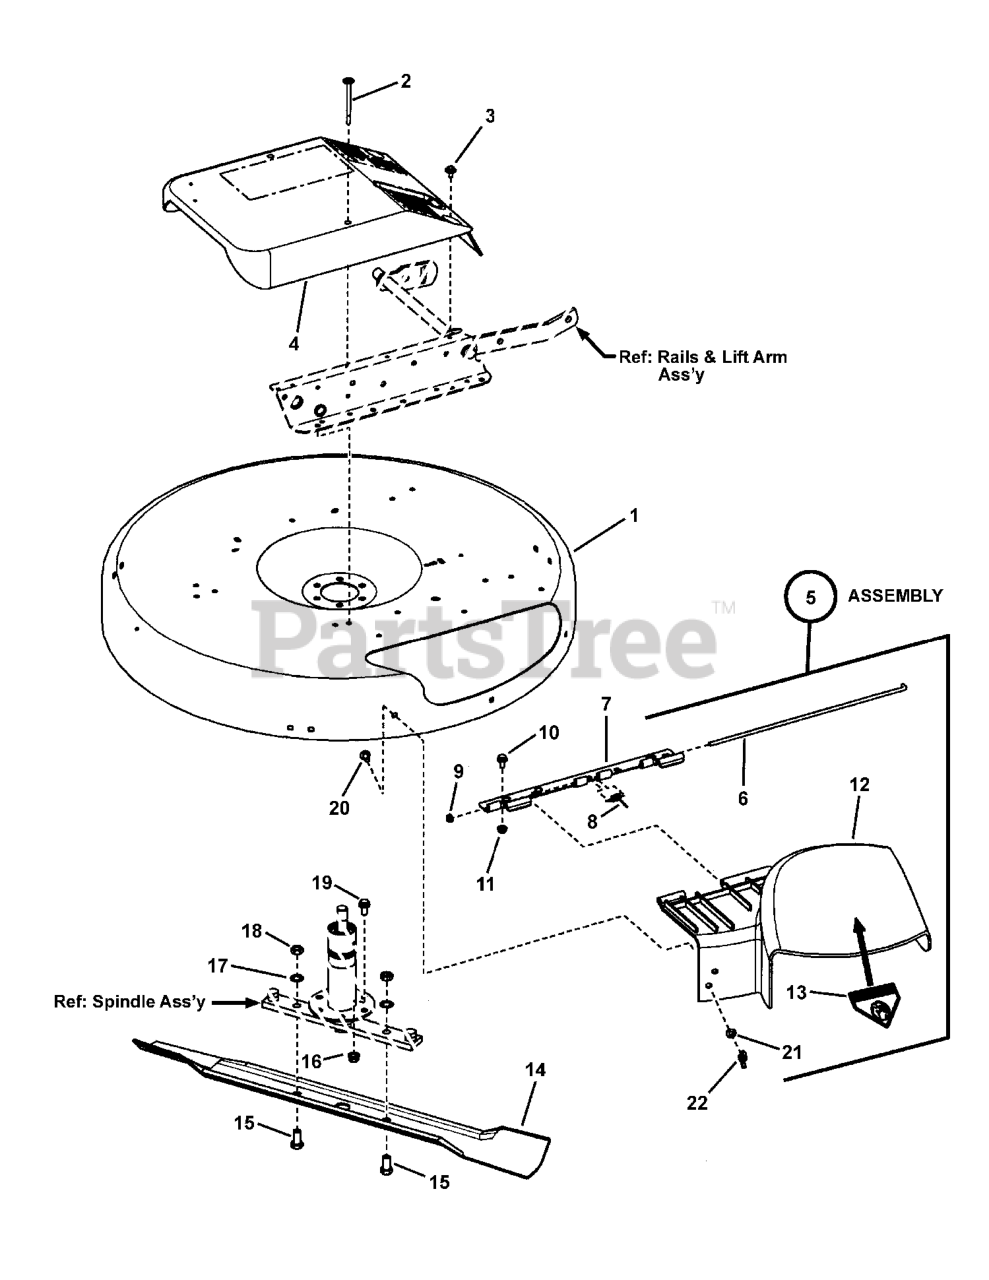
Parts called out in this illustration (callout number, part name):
1	DECK, 28" Replacement
2	SCREW, 1/4-20 x 3-1/2" Hex Head w/Free Spinning Washer
3	SCREW, 1/4-20 x 5/8" Hex Head w/Free Spinning Washer
4	COVER, Spindle
5	ASSEMBLY, Discharge Deflector, 28" without decal
6	PIN, Hinge
7	HINGE, Deflector (Deck side)
8	SPRING, Hinge
9	PUSH NUT, 1/4"
10	BOLT, 5/16-18 x 5/8" Hex Flange Lock, GR 5
11	NUT, 5/16-18 Hex Flange Lock, GR 5
12	DEFLECTOR, Discharge, 28"
13	DECAL, Danger, (Cut Finger)
14	BLADE, Replacement Kit, 28"
15	SCREW, 1/2-20 x 1-1/4" Hex Head Cap, GR 5
16	NUT, 3/8-16 Hex Flange Lock
17	WASHER, 1/2" Internal Tooth Lock
18	NUT, 1/2-20 Hex, GR 5 or B
19	BOLT, 3/8-16 x 3/4" Hex Flange Lock
20	BOLT, 5/16-18 x 3/4" Short Neck Carriage, GR 5
21	WASHER, 5/16" Flat
22	NUT, 5/16-18 Wing
